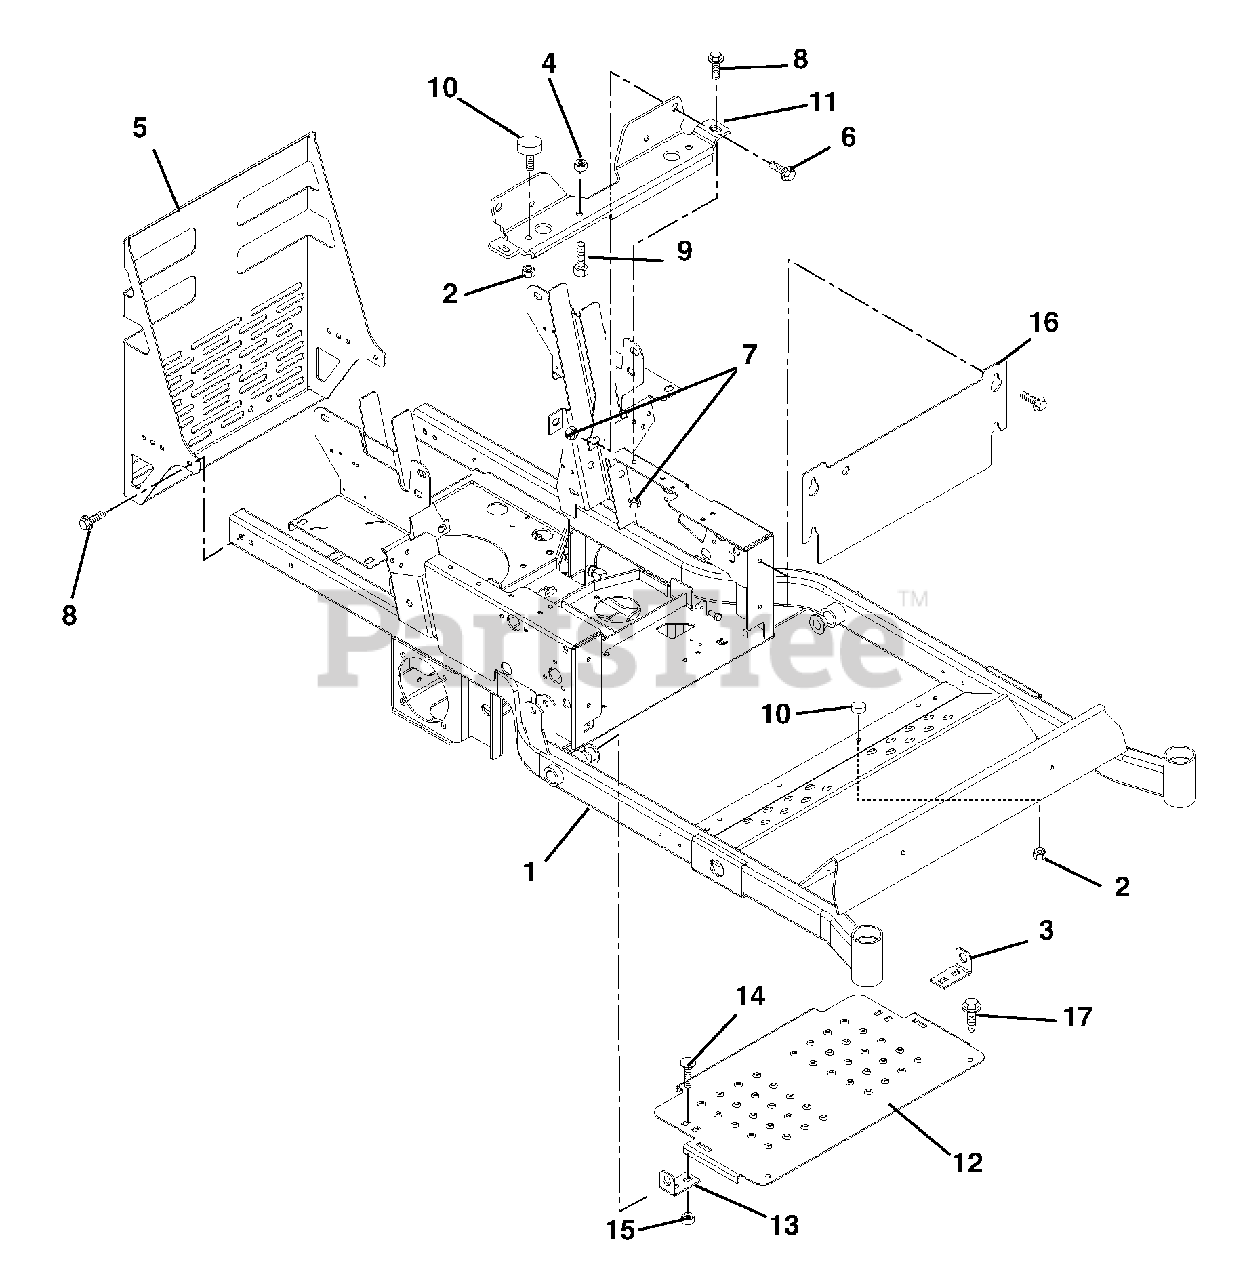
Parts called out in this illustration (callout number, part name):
1	Intermediate Z Frame (042, 043, 044, 054)
1	Intermediate Z Frame (051, 055)
2	Nut, Spin Lock Flange .312-18
3	Hinge, Footboard Left Hand
4	Nut, Locking Top Flange .31-18
5	Bumper/Guard
6	Bolt, Serrated Flange Washer Head .38-16 x 1.00
7	Nut, Retainer .375-16 x .37
8	Screw, Tapping Hex Washer Head .38-16 x .50
9	Bolt, Hex .31-18 x 1.25 Grade 5
10	Bumper, Rubber
11	Seat Support
12	Footrest Panel
13	Hinge, Footboard Right Hand
14	Bolt, Round Head Square Neck .38-16 x .75 Grade 5
15	Nut, Locking Top Flange .38-16
16	Access Panel
17	Screw, Tapping .38-16 x 1.00 Hex Washer Head (310, 311)
